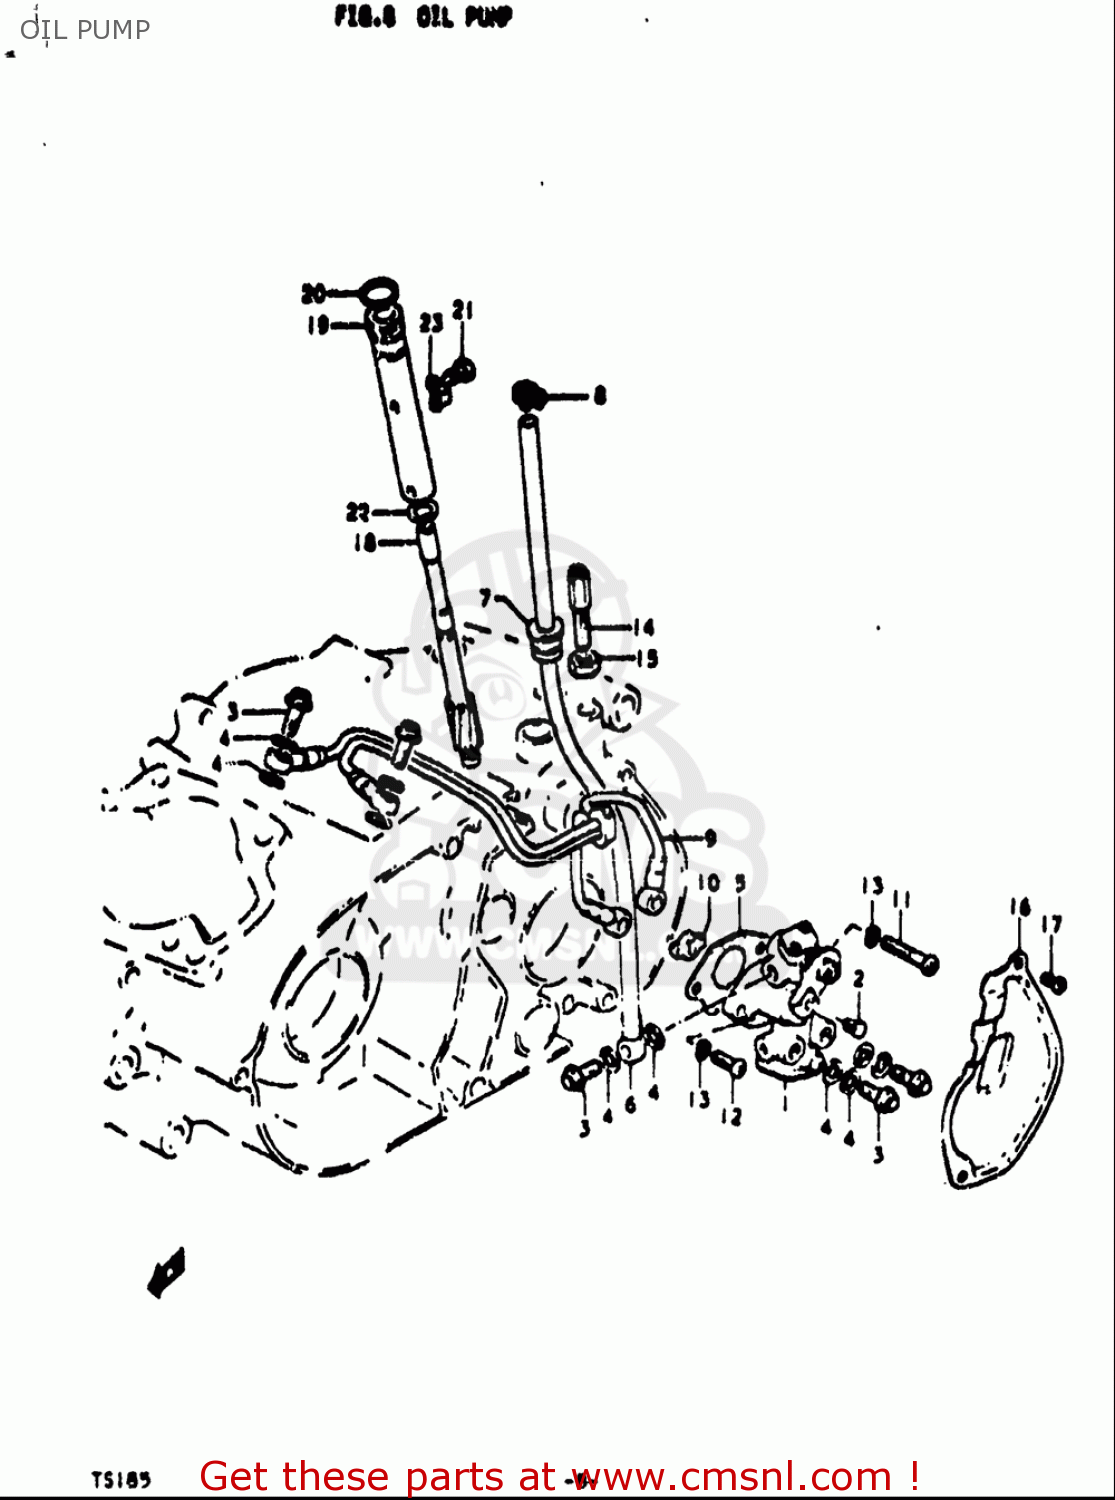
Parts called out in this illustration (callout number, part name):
1	PUMP ASSEMBLY,OIL
2	TERMINAL,CABLE
3	UNION BOLT
4	GASKET(6.2X11X1).2 (NAS)
5	GASKET,OIL PUMP (NAS)
6	HOSE,INLET
8	CLAMP
10	PIECE,OIL PUMP DRIVE
11	SCREW
12	SCREW
13	WASHER,LOCK
14	BOLT
15	NUT
16	CAP,OIL PUMP INSPECTION
17	SCREW
18	GEAR,TACHOMETER DRIVEN
19	SLEEVE,TACHOMETER DRIVEN GEAR
20	O RING(D:1.3,ID:9.6)
21	BOLT(6X12)
22	WASHER(6.5X16X1)
23	CLAMP
